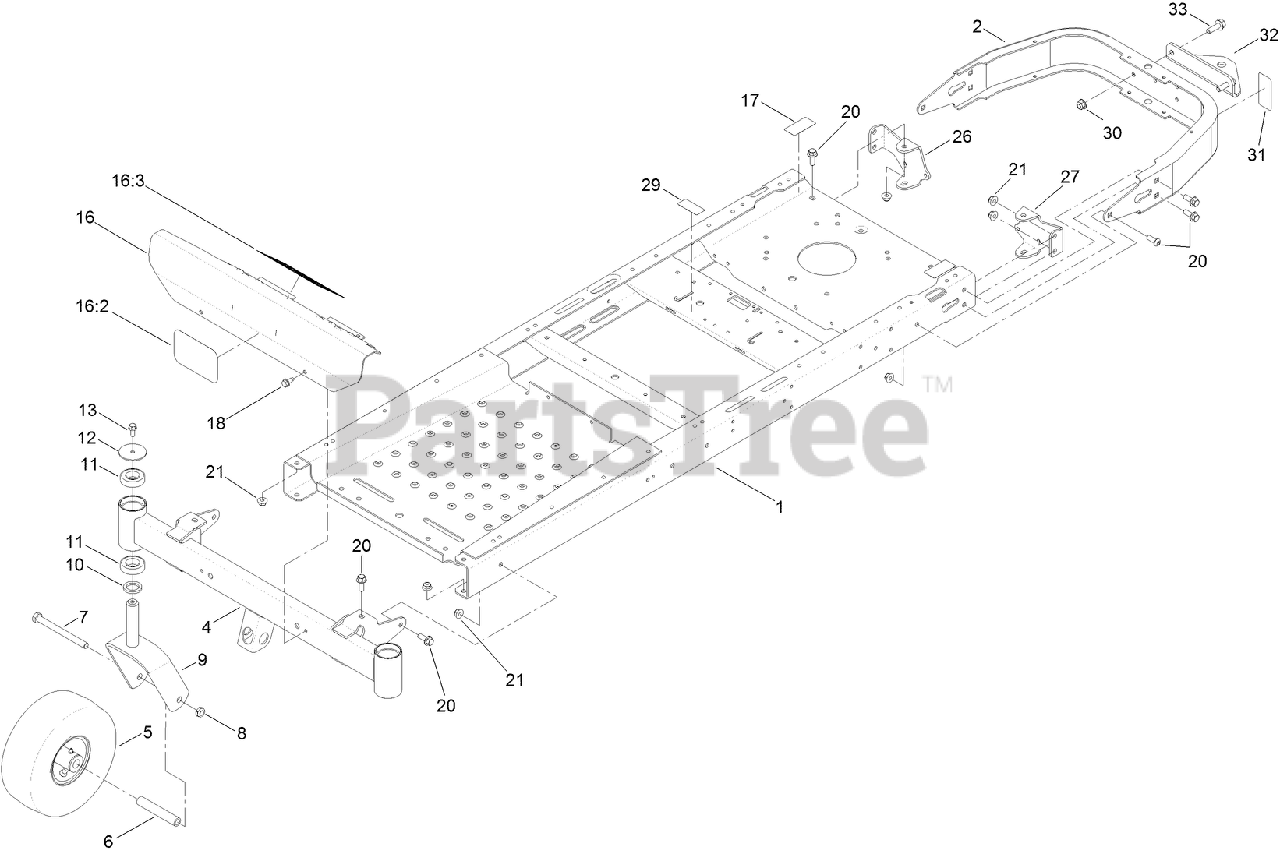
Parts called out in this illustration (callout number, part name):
2	BUMPER-REAR
4	AXLE-FRONT
5	CASTER WHEEL ASM
6	BUSHING-SPANNER
7	SCREW-HH
8	NUT-HEX
9	CASTER FORK ASM
10	WASHER-THRUST
11	BEARING-BALL
12	WASHER
13	SCREW-HHF
17	DECAL-BYPASS
18	SCREW-HWHTF
20	SCREW-HHF
20	SCREW-HSBH
21	NUT-HF, NI
26	MOUNT-HYDRO, REAR (RH)
27	MOUNT-HYDRO, REAR (LH)
29	DECAL-LOCATION, SERVICE DEALER
30	NUT-HF, NI
32	BRACKET-HITCH
33	SCREW-HHF
